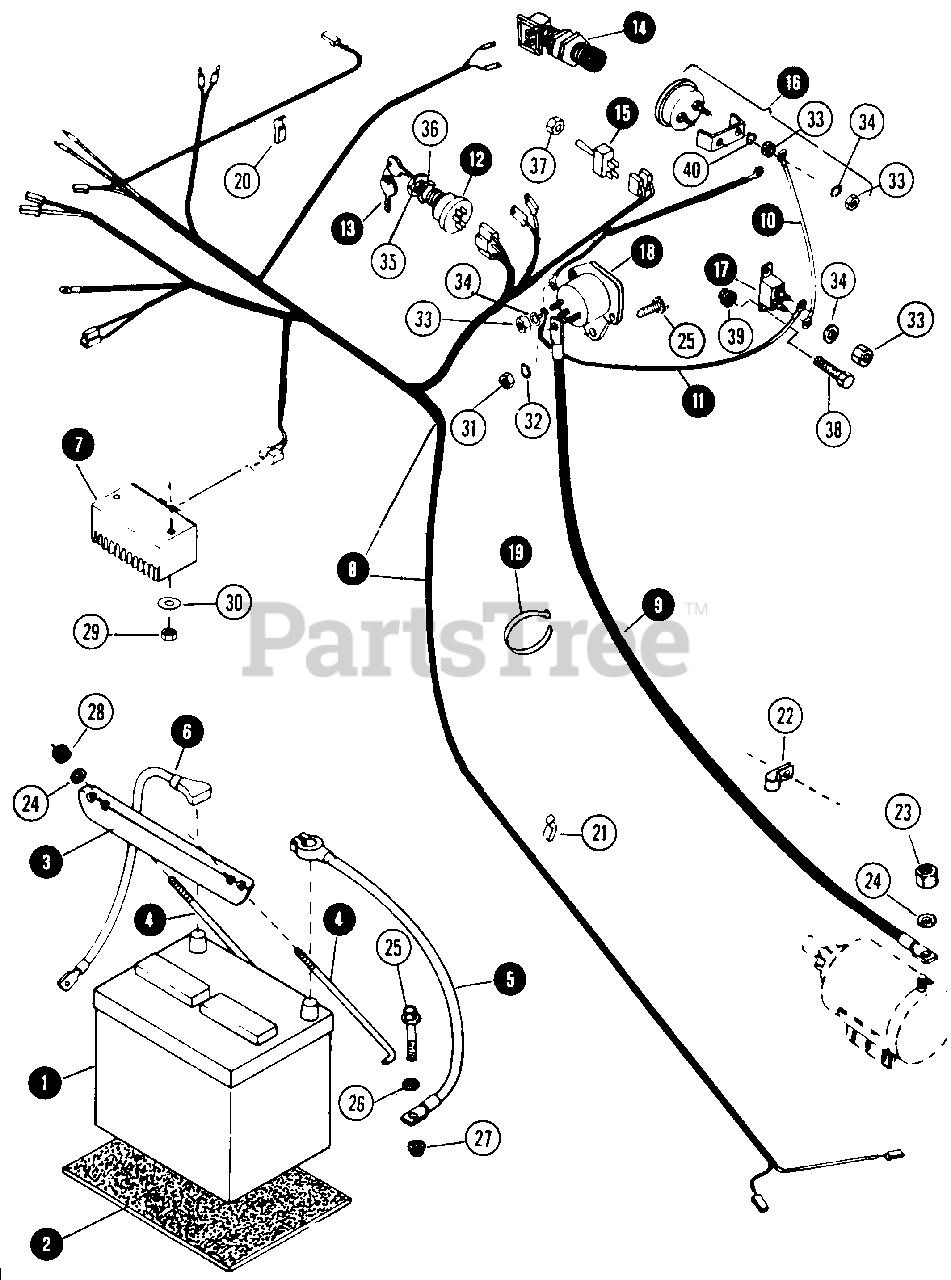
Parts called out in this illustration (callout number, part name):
1	BATTERY, 12 VOLT, 52 AMP HOUR
2	PAD, BATTERY
3	CLAMP, BATTERY HOLD DOWN
4	ROD, HOLD DOWN
5	CABLE, BATTERY - NEGATIVE TO GROUND
6	CABLE, BATTERY POSITIVE - TO SOLENOID
7	RECTIFIER - REGULATOR
8	HARNESS, MAIN WIRING
9	CABLE, SOLENOID TO STARTER
10	WIRE, CIRCUIT BREAKER TO AMMETER
11	WIRE, SOLENOID TO CIRCUIT BREAKER
12	SWITCH, IGNITION
13	KEY, IGNITION SWITCH (PAIR)
14	SWITCH, INTERLOCK (Seat / Rear PTO)
15	SWITCH, TOGGLE PTO
16	AMMETER ASSEMBLY
17	BREAKER, CIRCUIT
18	SOLENOID, STARTING
19	STRAP, WIRE RETAINING
20	CLIP, WIRING
21	CLIP, WIRING
22	CLIP, WIRING
23	NUT, 1/4C HEX LOCK
24	WASHER 1/4 FLAT
25	BOLT 1/4C x 5/8 HEX FLANGE LOCK
26	WASHER, 1/4 EXTERNAL TOOTH LOCK
27	NUT, 1/4C HEX FLANGE LOCK
28	NUT, 1/4C HEX LOCK
29	NUT, 1/4C HEX
30	WASHER, 1/4 INTERNAL LOCK
31	NUT, 5/16C HEX
32	WASHER 5/16 LOCK
33	NUT, #10-32 HEX
34	WASHER, #10 LOCK
35	NUT, SWITCH MOUNTING
36	WASHER, 5/8 FLAT
37	NUT, 1/2-27 HEX-SPECIAL
38	SCREW, #10-24 x 1/2 PAN HEAD
39	NUT, #10-24 FLANGE LOCK
40	WASHER, #10 FLAT
